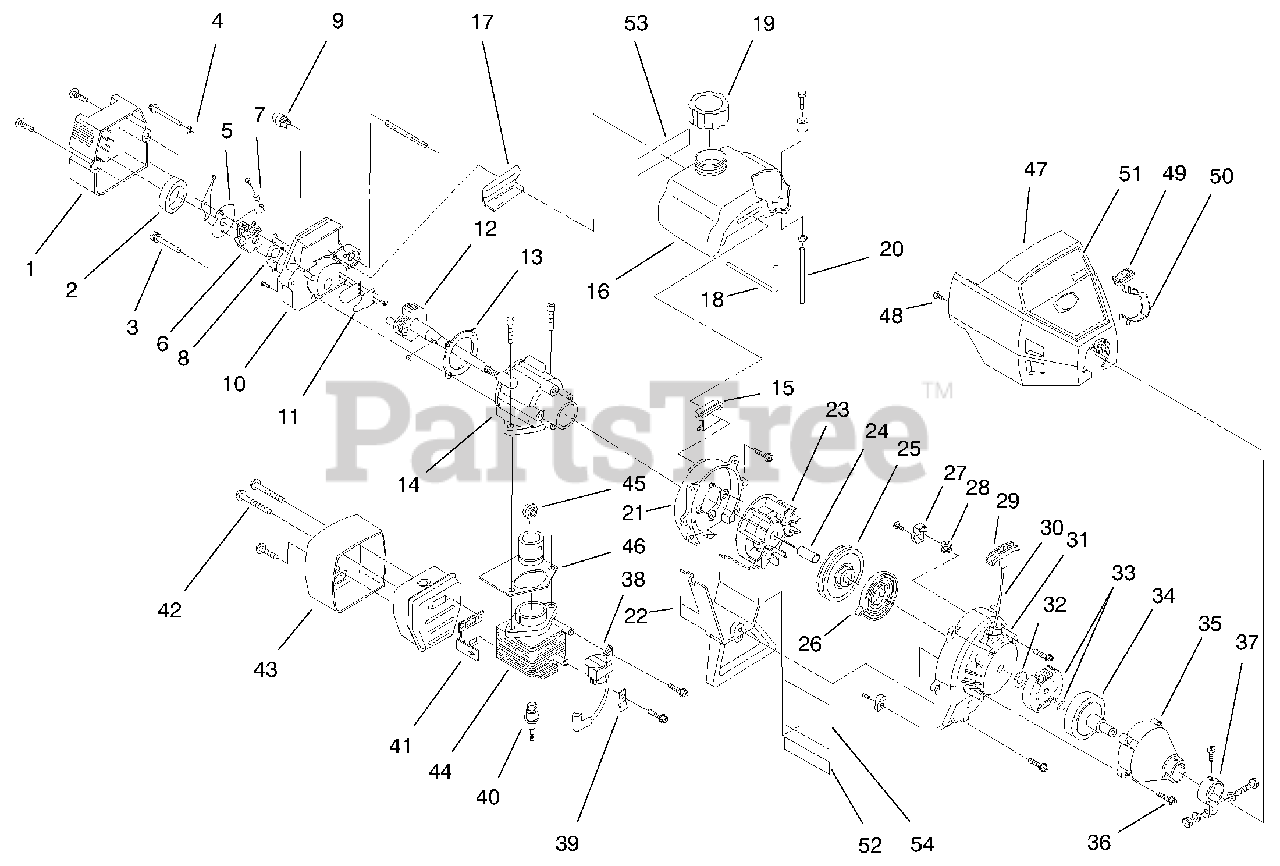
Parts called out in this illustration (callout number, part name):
1	Carburetor/Air Cleaner Asm. (Incl. Ref. #2)
2	Air Cleaner Filter
3	Carburetor Mounting Screw Asm.
4	Wavey Washer
5	Choke Lever & Plate
6	Carburetor Asm.
7	Throttle Adj. Asm. (Walbro)
7	Throttle Adj. Asm. (Zama)
8	Carburetor Gasket
9	Primer & Hose Asm.
10	Carburetor Mount Asm.
11	Reed Asm.
12	Power Shaft Asm.
13	Carburetor Mount Gasket
14	Crankcase Service Asm. (Incl. Ref. #12)
15	Front Mounting Pad
16	Fuel Tank Asm. (Incl. Ref. #18-20)
17	Rear Mounting Pad
18	Return Line
19	Fuel Cap Asm.
20	Fuel Line Asm.
21	Shroud Asm.
22	Shroud Extension & Stand
23	Flywheel Asm.
25	Recoil Pulley Asm.
26	Recoil Spring
27	Pulley Retainer Asm.
28	Rope Guide
29	Pull Handle
31	Starter Housing Asm.
32	Clutch Washer
33	Clutch Rotor Asm.
34	Clutch Drum Asm.
35	Clutch Cover Asm.
36	Clutch Cover Screw Asm.
37	Upper Clamp Asm
38	Module Asm.
39	Ground Tab
40	Spark Plug
41	Exhaust Gasket
42	Muffler Mounting Bolt Asm.
43	Muffler Asm. (Incl. Ref. #41)
44	Cylinder Asm.
45	Piston and Rod Asm.
46	Cylinder Gasket
47	Engine Cover
48	Engine Cover Screw
50	Lead Wires
51	Decal-Toro Housing
52	Decal-Warning
53	Decal-Fuel & Oil Mix
54	Decal-Carb.
